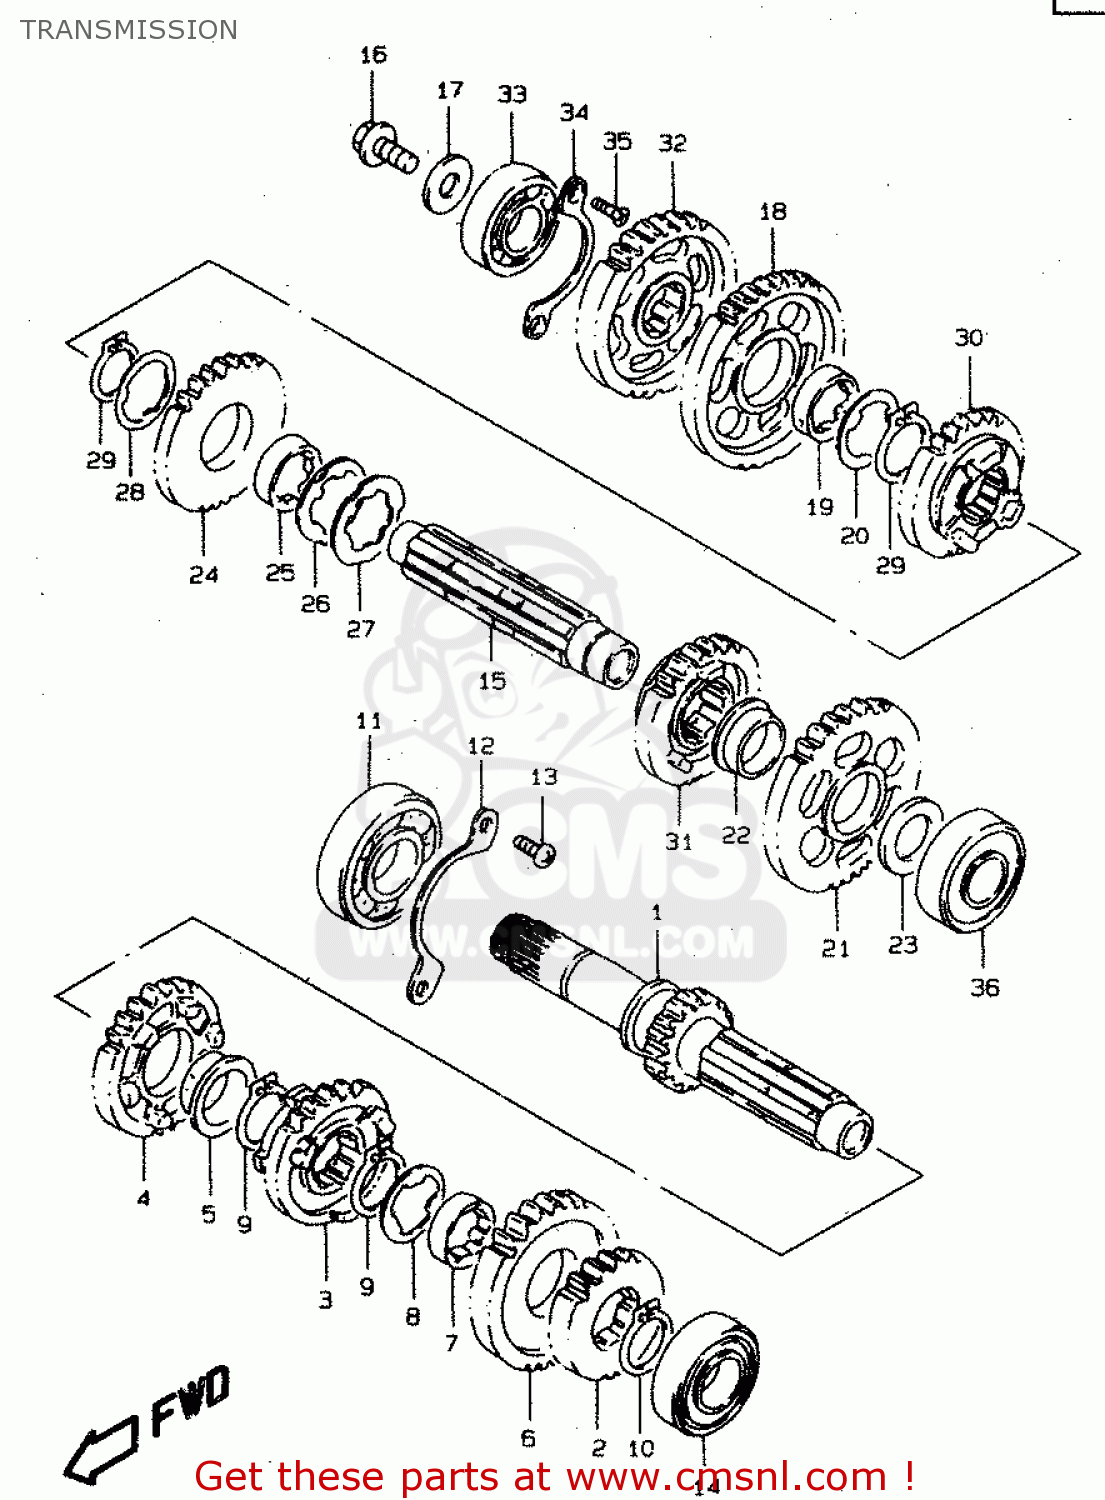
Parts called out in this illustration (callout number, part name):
1	COUNTERSHAFT(NT:14)
2	GEAR,2ND DRIVE(NT:19)
3	GEAR,3RD DRIVE(NT:22)
4	GEAR,4TH DRIVE(NT:25)
5	BUSHING
6	GEAR,5TH DRIVE
7	BUSHING
8	WASHER,LOCK
9	RING,SNAP
10	CIRCLIP
11	BEARING(25X62X17)
12	RETAINER,CNTR SHAFT BEARING
13	SCREW
14	BEARING 20X47X14
15	SHAFT,DRIVE
16	NOZZLE,DRIVE SHAFT
17	WASHER
18	GEAR,1ST DRIVEN(NT:32)
19	BUSH
20	WASHER,LOCK
21	GEAR,2ND DRIVEN(NT:31)
22	BUSH
23	SHIM(20X34X1)
24	GEAR,3RD DRIVEN(NT:27)
25	BUSH
26	WASHER
27	WASHER,LOCK
28	WASHER,LOCK
29	CIRCLIP
30	GEAR,4TH DRIVEN(NT:25)
31	GEAR,5TH DRIVEN
32	GEAR,REDUCTION DRIVE(NT:30)
33	BEARING(20X52X15)
34	RETAINER,DRIVE SHAFT BEARING
35	SCREW
36	BEARING(20X52X15)
